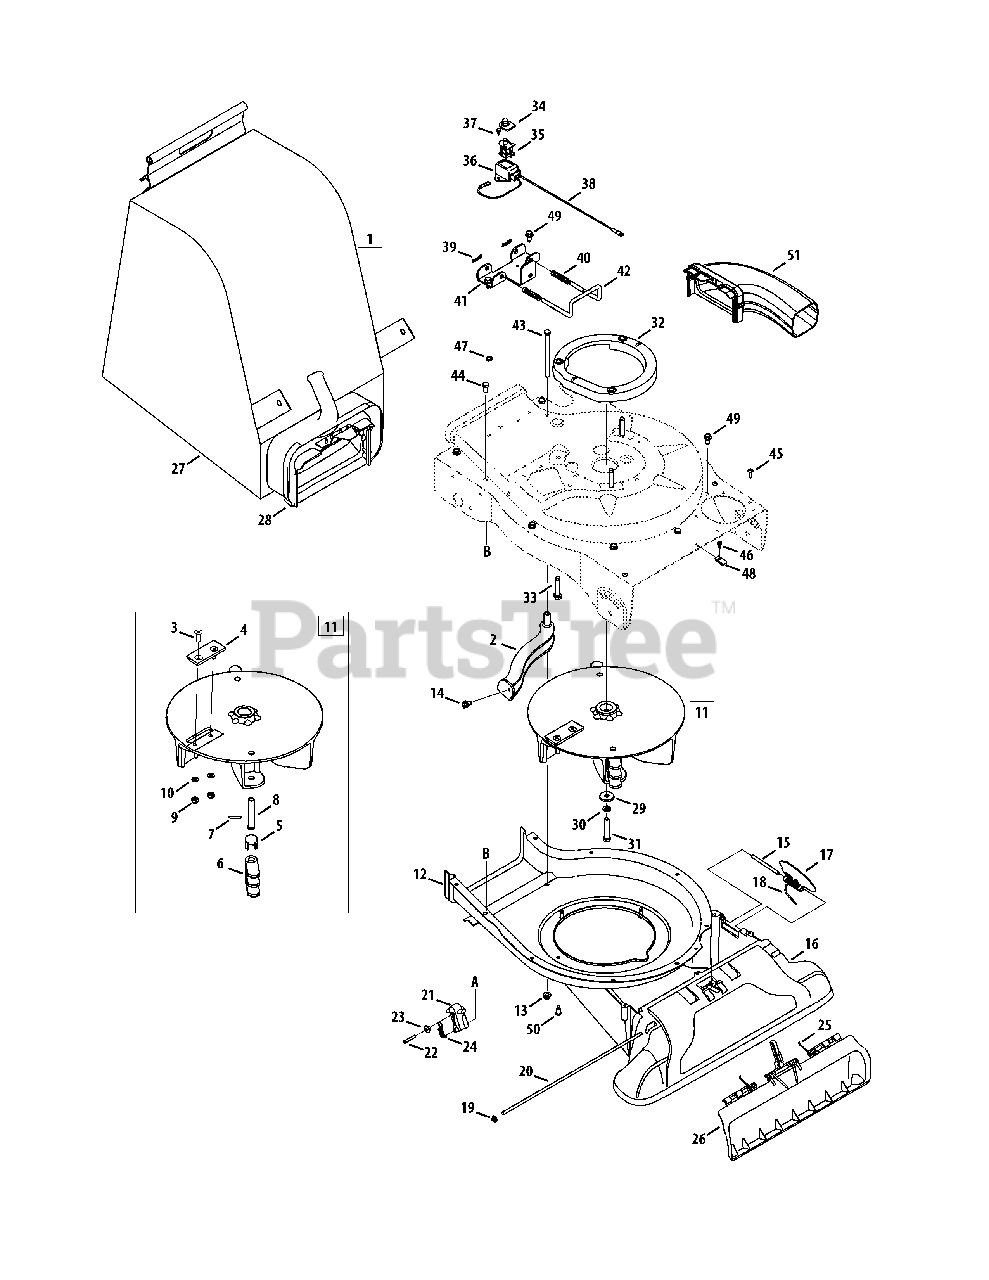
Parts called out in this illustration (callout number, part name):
1	Bag Assembly
2	Screen Assembly
3	Hex Screw 5/16-24 x 1.0
4	Chipper Blade
5	Pin Clip
6	Flail
7	Spiral Pin
8	Clevis Pin
9	Lock Nut, 5/16-24
10	Lock Washer, 5/16
11	Impeller Assembly
12	Lower Flail Housing
13	Flange Lock Nut 5/16-18
14	Screw, 5/16-18 x.500
15	Hinge Pin
16	Nozzle
17	Base Adapter Door
18	Torsion Spring
19	Cap Speed Nut 1/4
20	Pivot Rod
21	Nozzle Door Lever
22	Hex Screw, #8-18 x 1.25
23	Shoulder Spacer
24	Extension Spring
25	Nozzle Door Torsion Spring
26	Nozzle Door
27	Bag
28	Chute Assembly
29	Flat Washer.375 ID x 1.25 OD
30	Lock Washer 3/8
31	Hex Cap Screw, 3/8-24 x 2.75
32	Engine Spacer Assembly
33	Screw, 3/8-16 x 1.875
34	Switch Cover
35	Safety Switch
36	Safety Switch Cover
37	Hex Washer Screw #10-16 x.50
38	Wire Harness
39	Cotter Pin
40	Compression Spring
41	Mounting Bracket
42	Lock Rod
43	Hex Cap Screw 5/16-18 x 4.5
44	Hex Cap Screw 5/16-18 x.625
45	Screw, #12-16 x.750
46	Screw #10 - 16 x.500
47	External L-Washer 5/16
48	Speed Nut
49	Hex Index Screw, 5/16-12 x.750
50	Shoulder Screw, #12-24 x .30 x .46
51	Blower Chute
